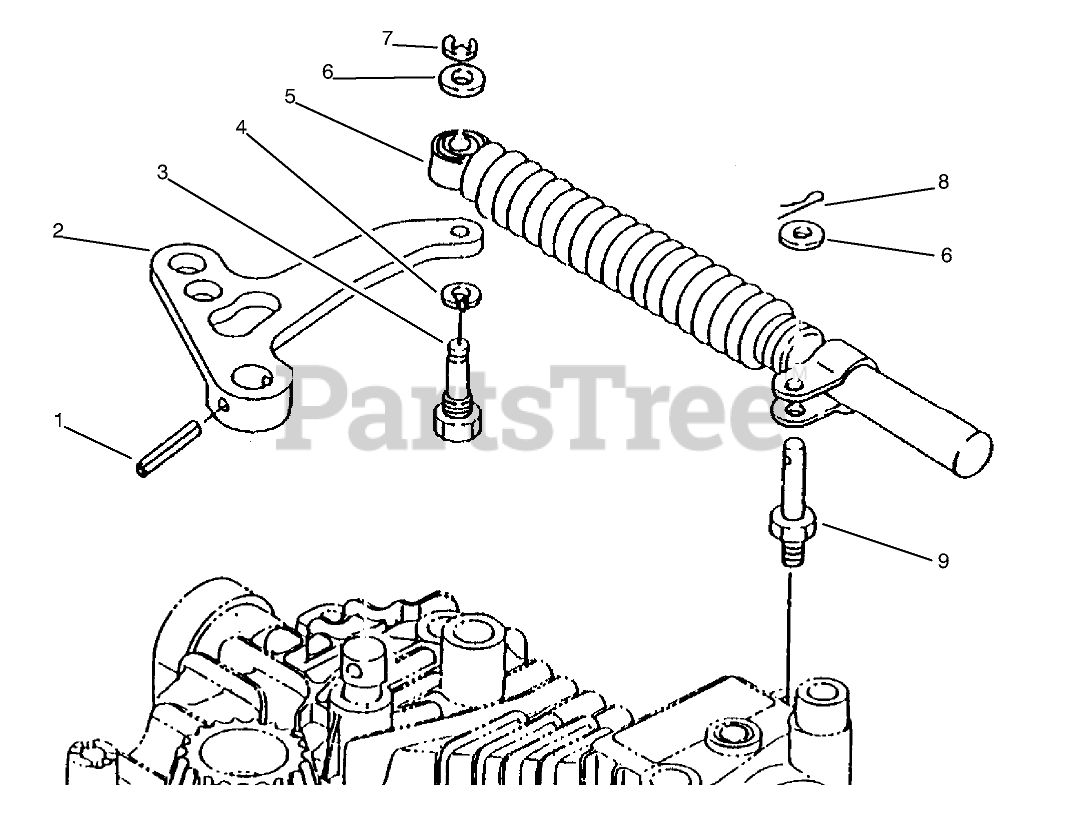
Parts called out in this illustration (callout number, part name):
1	PIN-ROLL
4	WASHER
5	ABSORBER - SHOCK
6	WASHER
8	PIN-COTTER
